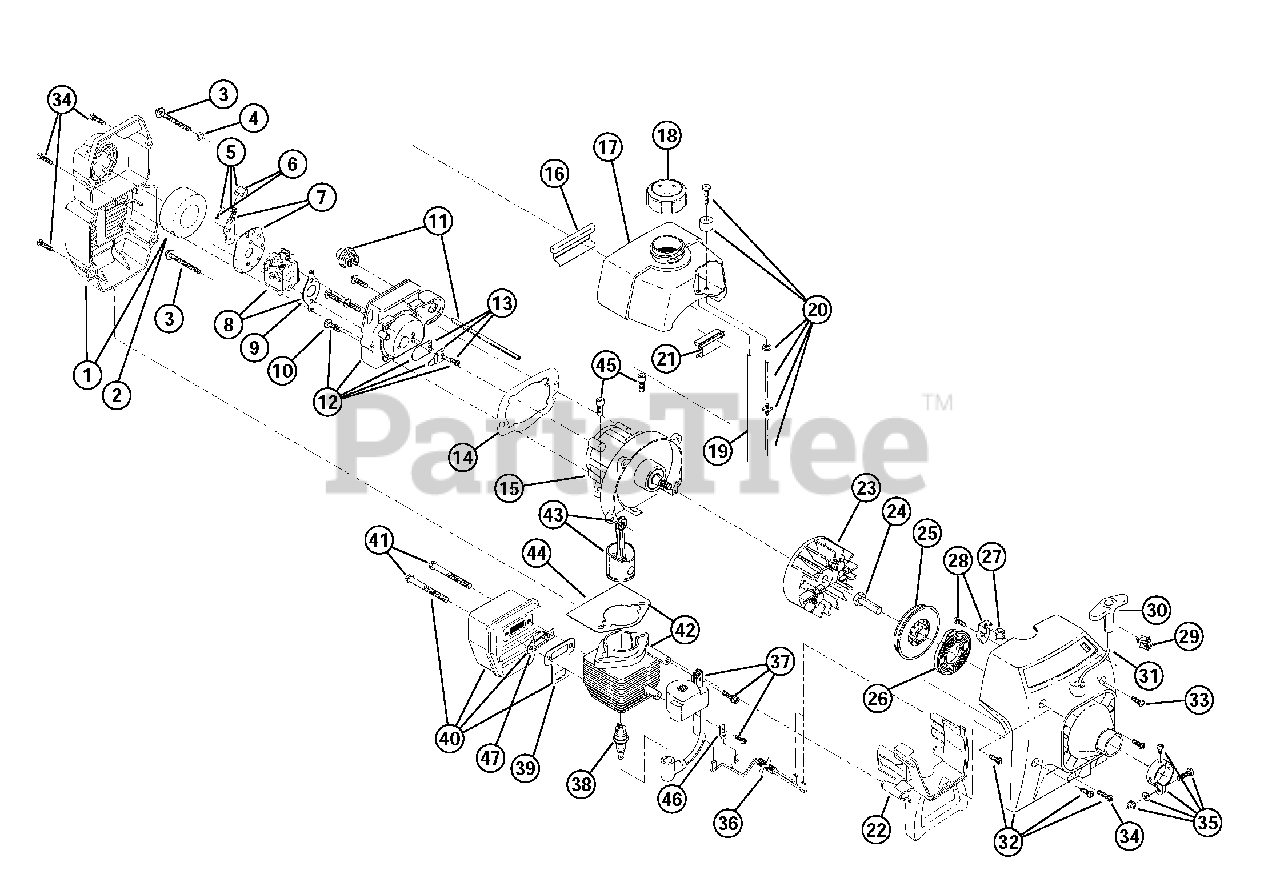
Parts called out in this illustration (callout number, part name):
1	Air Cleaner/Muffler Cover Assembly
2	Air Cleaner Filter
3	Carburetor Mounting Screw Assembly
4	Wavey Washer
5	Choke Lever Assembly
6	Choke Knob and Screw
7	Choke Lever and Plate
8	Carburetor Assembly
9	Carburetor Gasket
10	Carb Mount Screw
11	Primer and Hose Assembly
12	Carb Mount Assembly
13	Reed Assembly
14	Carburetor Mount Gasket
15	Crank Case Service Assembly
16	Rear Mounting Pad
17	Fuel Tank Assembly
18	Fuel Cap Assembly
19	Fuel Return Line
20	Fuel Line Assembly
21	Front Mounting Pad
22	Shroud Extension and Stand
23	Flywheel Assembly
24	Square Nut Drive
25	Recoil Pulley Assembly
26	Recoil Spring
27	Rope Guide
28	Pulley Retainer Assembly
29	Switch Assembly
30	Pull Handle
32	Starter Housing Assembly
33	Housing Screw
34	Cover Screw
35	Upper Clamp Assembly
36	Wire Lead
37	Module Assembly
38	Spark Plug
39	Exhaust Gasket
40	Muffler Assembly
41	Muffler Mounting Bolt Assembly
42	Cylinder Assembly
43	Piston and Rod Assembly
44	Cylinder Gasket
45	Cylinder Bolt
46	Ground Tab
47	Spark Arrestor
